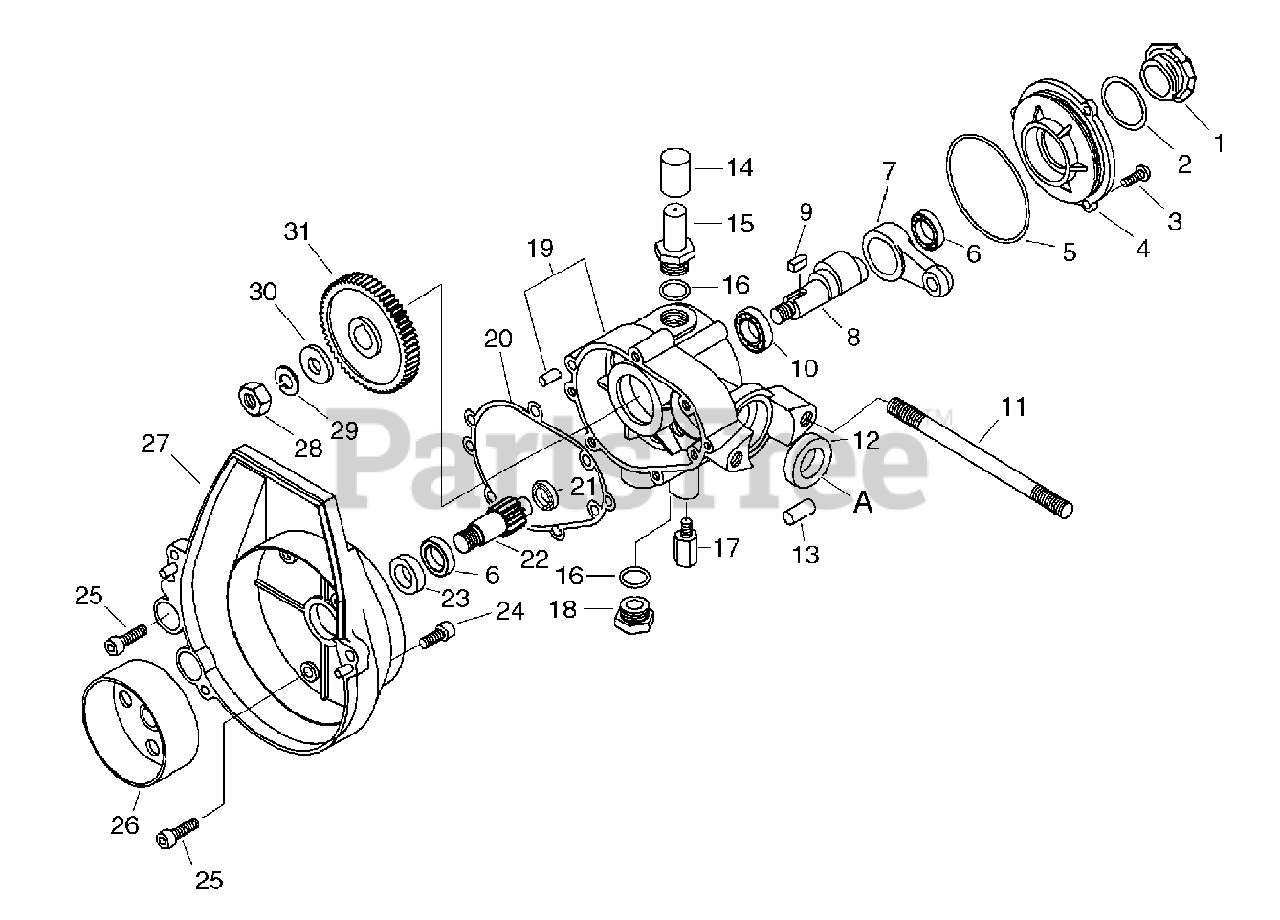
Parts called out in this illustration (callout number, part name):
1	Oil Gauge
3	Screw 4x12
4	Gear Case Lid
7	Connecting Rod
8	Crank Shaft
10	Bearing, Ball 6201
11	Stud Bolt
12	Oil Seal
13	Piston Pin
15	Oiling Bolt
16	O-Ring P-10A
18	Drain Cap
19	Pump Body W/Pin
22	Pinion Shaft
23	Oil Seal
24	Bolt, H.S. 5x18
25	Bolt, H.S. 5x25
26	Clutch Drum
27	Fan Cover
29	Washer, Spring 8
30	Washer 8
31	Spur Gear
